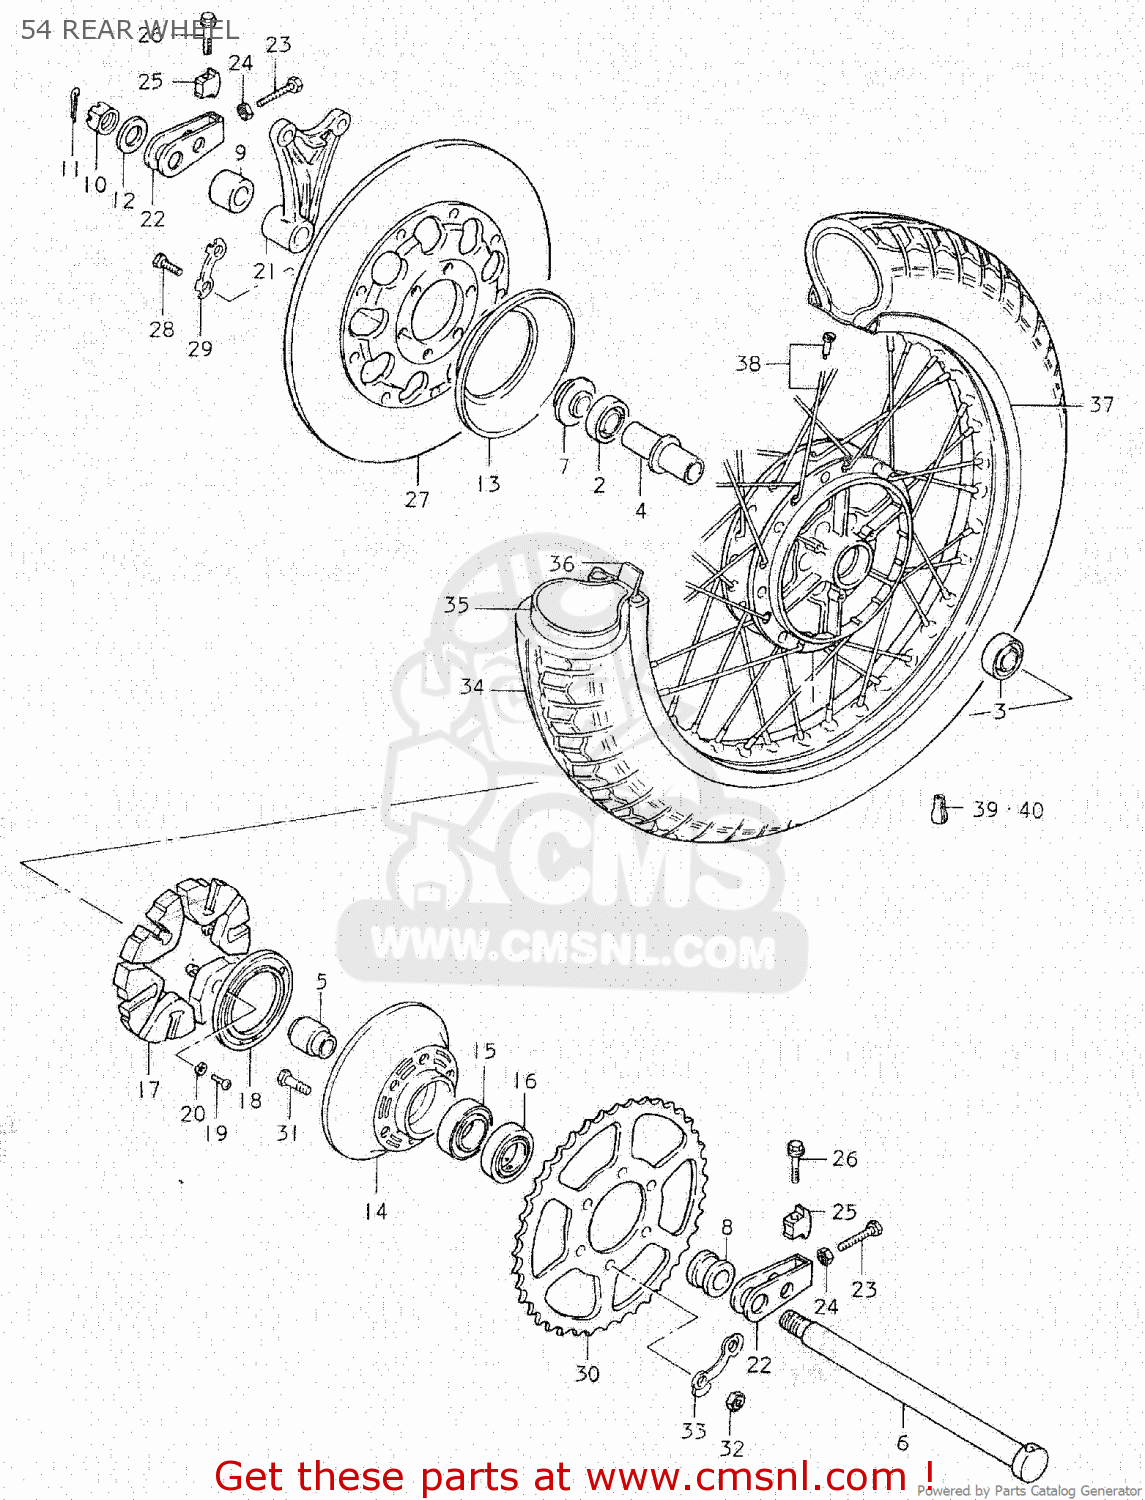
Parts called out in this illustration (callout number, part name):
1	DRUM,REAR HUB
2	BEARING
3	BEARING, LH
4	SPACER,REAR HUB BEARING
5	SPACER,REAR HUB BEARING
6	AXLE,REAR
7	SPACER,REAR AXLE
8	SPACER(20X33X28.3)
9	SPACER(20X38X12)
10	NUT 18MM
11	PIN,COTTER
12	WASHER(19X34X4)
13	COVER,REAR WHEEL HUB
14	DRUM,REAR SPROCKET MOUNT
15	BEARING
16	SEAL,OIL(33X62X7)
17	ABSORBER,REAR HUB SHOCK
18	PLATE,REAR HUB SHOCK ABSORBER
19	SCREW
20	LOCK WASHER
21	BRACKET,REAR CALIPER
22	ADJUSTER,CHAIN
23	BOLT
24	NUT
25	SUPPORTER,CHAIN ADJUST
26	BOLT (8X40)
27	DISC,REAR BRAKE
28	BOLT(8X25)
29	WASHER
30	SPROCKET,REAR
31	BOLT
32	NUT
33	WASHER
34	TIRE
35	TUBE ASSEMBLY,WHEEL,INNER
36	PROTECTOR,WHEEL,INNER
37	RIM,WHEEL
38	SPOKE SET,REAR
39	BALANCER,WHEEL (B)
40	BALANCER,WHEEL (30G)
